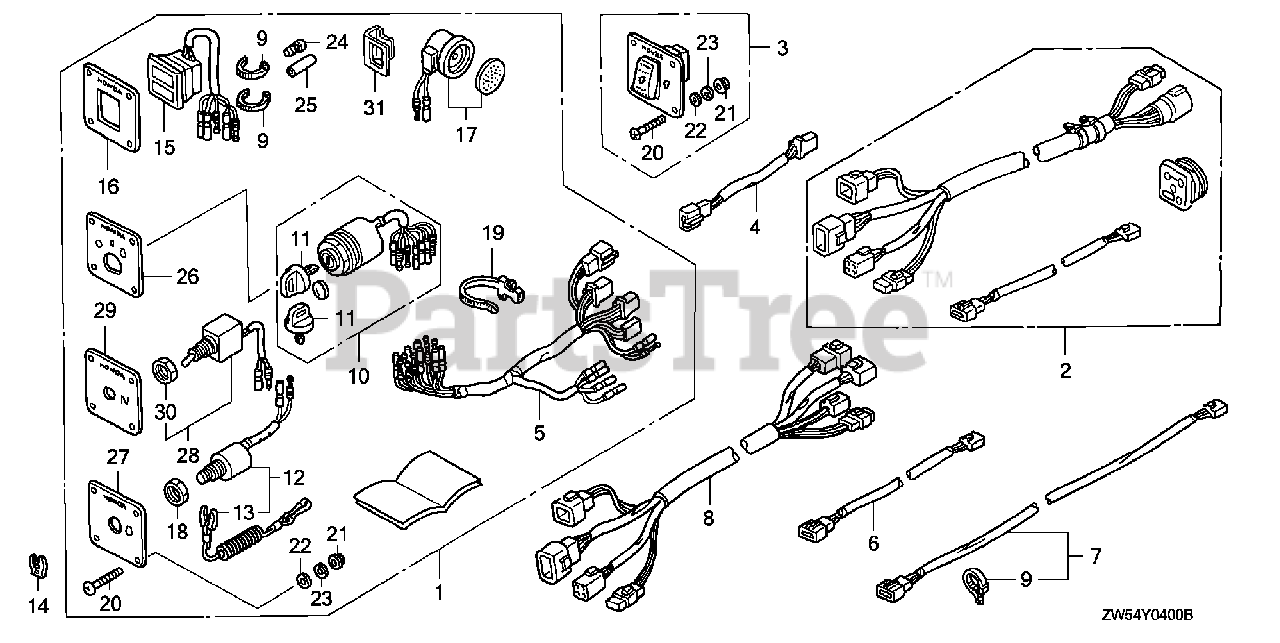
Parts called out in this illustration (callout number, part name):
1	PANEL KIT, CONTROL (B)
2	CABLE KIT, SWITCH INDICATOR
3	SWITCH KIT, LIGHT
4	SUB-HARNESS ASSY., POWER
5	HARNESS ASSY., SWITCH PANEL
6	CABLE ASSY., EXTENSION
7	CABLE ASSY., EXTENSION
8	CABLE ASSY., EXTENSION
9	TIE, CABLE (NATURAL 2.4X92)
10	SWITCH ASSY., COMBINATION
11	KEY ASSY., COMBINATION SWITCH
12	SWITCH ASSY., EMERGENCY STOP
13	WIRE, EMERGENCY
14	CLIP, EMERGENCY LOCK
15	LAMP ASSY., INDICATOR (2-LED)
16	PANEL, INDICATOR
17	BUZZER, WARNING
18	NUT, HEX. (16MM)
19	BAND, WIRE HARNESS (150MM)
20	SCREW, PAN (5X40)
21	NUT, FLANGE (5MM)
22	WASHER, PLAIN (5MM)
23	WASHER, SPRING (5MM)
24	PLUG, CONNECTOR (INNER)
25	PLUG, CONNECTOR (OUTER)
26	PANEL, SWITCH
27	PANEL, EMERGENCY STOP SWITCH
28	SWITCH ASSY., SOLENOID
29	PANEL, SOLENOID
30	NUT, HEX. (12MM)
31	BRACKET, BUZZER
